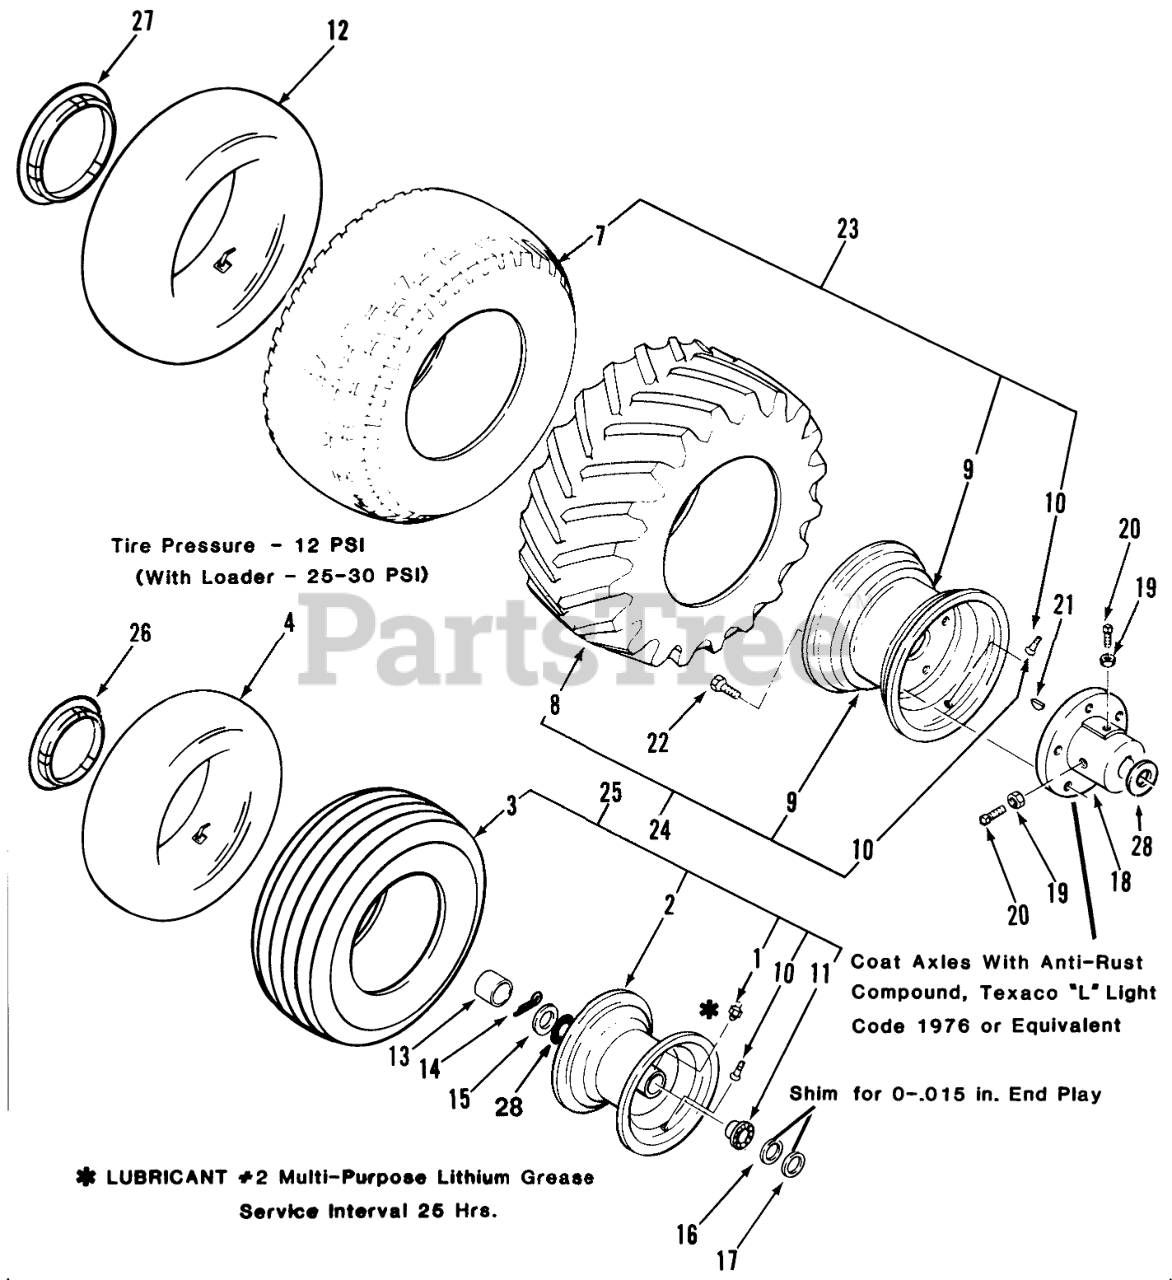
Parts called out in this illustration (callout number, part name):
1	ZERK-GREASE
2	Front Wheel (Includes Item 1, 10 & 11 Used on 310 & 312)
3	TIRE-15 X 6.00-6
7	TIRE-23X8.50-12 2PLY
8	Tire-Cleat, Rear
9	WHEEL
10	VALVE
11	BEARING-WHEEL
12	INNER TUBE
13	HUB CAP-FLAT BLACK
14	COTTER PIN-4
15	WASHER-WHEEL
16	WASHER
17	WASHER-SHIM
18	Hub Rear
19	Nut
20	Screw-Set
21	KEY-WOODRUFF
22	Lug Nut
23	ASM-Wheel & Tire
24	ASSY WHEEL & TIRE
25	ASM-Wheel & Tire
26	6"-HUB CAP LOGO
27	12"-HUB CAP LOGO
28	WASHER-THRUST
